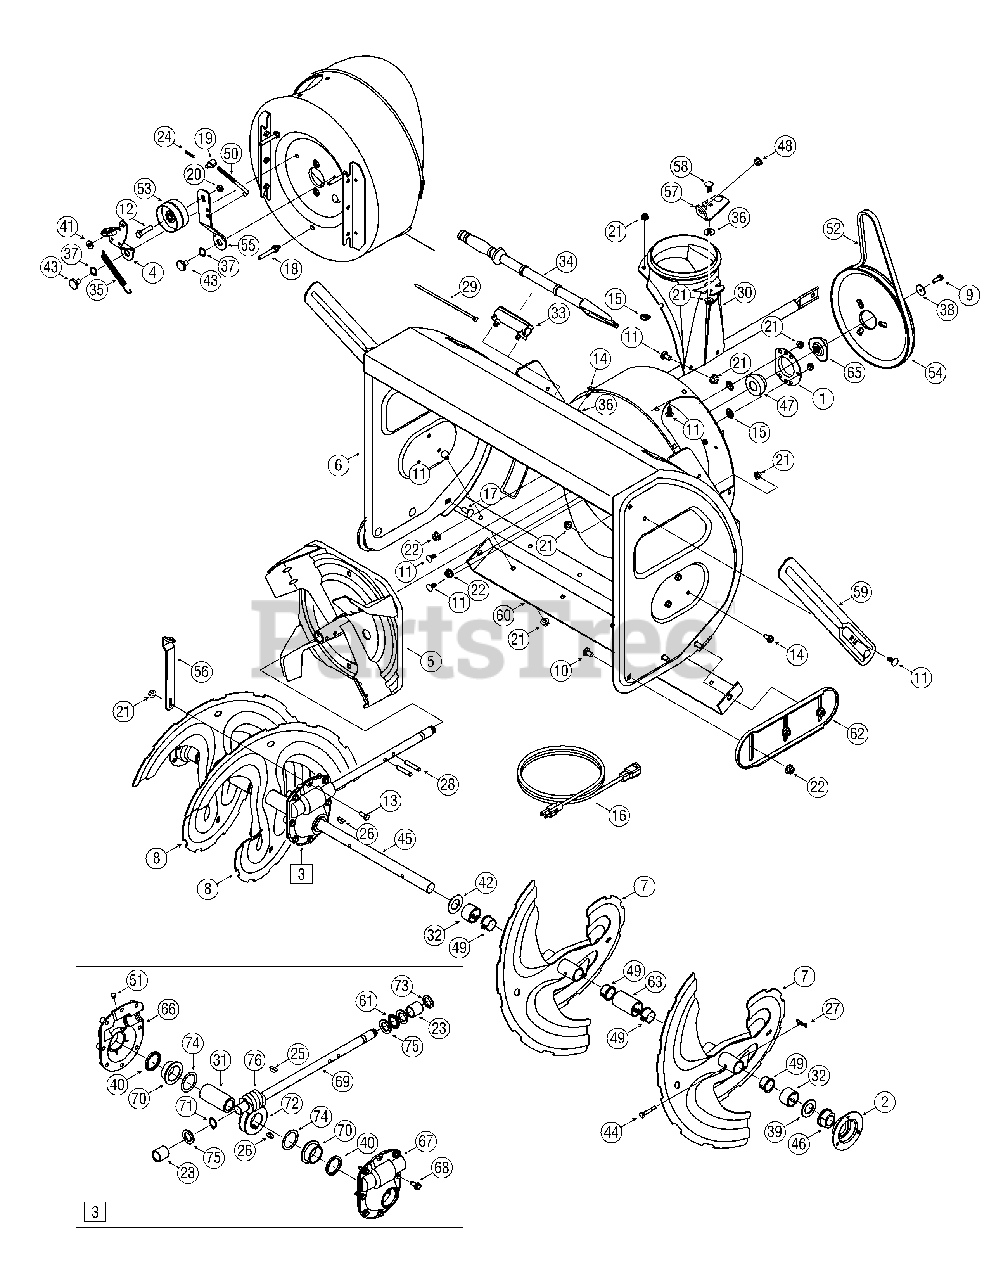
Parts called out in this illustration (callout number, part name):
1	Housing, Bearing
3	Gear Box Assembly, Auger
4	Bracket Assy, Auger Brake
5	Impellar, 16"
6	Housing, Auger - 33"
7	Spiral Assy, LH
8	Spiral Assy, RH
9	Screw, 5/16-24 x .875
10	Bolt, Carriage, 3/8-16 x .750
11	Screw, Carriage, 5/16-18 x .75
12	Scr, Hex Cap, 3/8-16 x 1.75
13	Scr,Hex Cap, 5/16-18 x 1.00
14	Screw, 5/16-18 x .750
15	Nut, Push
16	Extension Cord, 110V
17	Bolt, Carriage, 3/8-16 x 1.0
18	Screw, 5/16-18 x .4300
19	Ferrule
20	Nut, Hex Lock, 3/8-24
21	Nut, Flnge Lk, 5/16-18
22	Nut, Flg Lk, 3/8-16
23	Sleeve
24	Pin, Internal Cotter
25	Key, Hi Pro, 3/16 x 3/4
26	Key, Woodruff,1/4 x 3/4
27	Pin, Bowtie Cotter
28	Pin, Spirol, 5/16 x 1.75
29	Tie, Cable
30	Adapter, Chute, 6"
31	Shf, Gear, Worm
32	Spacer, 1.0 x 1.5 x 1
33	Clip, Mounting
34	Tool, Cleanout
35	Spring, Extension
36	Washer, .349 x .879 x .063
37	Washer, .625 x .885 x .015
38	Washer, Flat, .34 x 1.50 x .150
39	Spacer, 1.004 x 1.375 x .25
40	Oil Seal
41	Washer, .344 x .75 x .12
42	Washer, 1.01 x 1.86 x .06
43	Screw, Shoulder, .625 x .17
44	Pin, Shear, .25 x 1.75
45	Axle, Spiral, 33"
46	Bearing, Flange w/Flats
47	Bearing, Self Aligning
48	Bushing, Nylon
49	Bushing, Flange, 1.051 x 1.16
50	Rod, Auger Idler
52	V Belt,1/2 x 42
53	Pulley, Flat Idler, 2.75 OD
54	Pulley, Auger Drive, 10.0
55	Bracket, Auger Idler
56	Bracket, Gear Box Support
57	Bracket, Chute Crank
58	Screw, Carriage, 5/16-18 x 1.00
60	Plate, Shave, 33"
61	Brg, Thrust
62	Shoe, Skid
63	Spacer, 1.0 x 1.5 x 2
64	Screw, 5/16-18 x .75
65	Pulley, Adapter, .75 Dia.
66	Hsg Assy Auger RH
67	Hsg Assy Auger LH
68	Screw, LD, 5/16-18 x .750
69	Shf, Drive, Auger
70	Flange Bearing
71	Ext, Ret, Ring
72	Gear, Worm, LH
73	Seal, Oil
74	Washer, Flat, 1.52 ID x 2.0 OD
75	Washer, Flat, .88 ID x .38 OD
76	Gear, Worm, Dbl Thread
